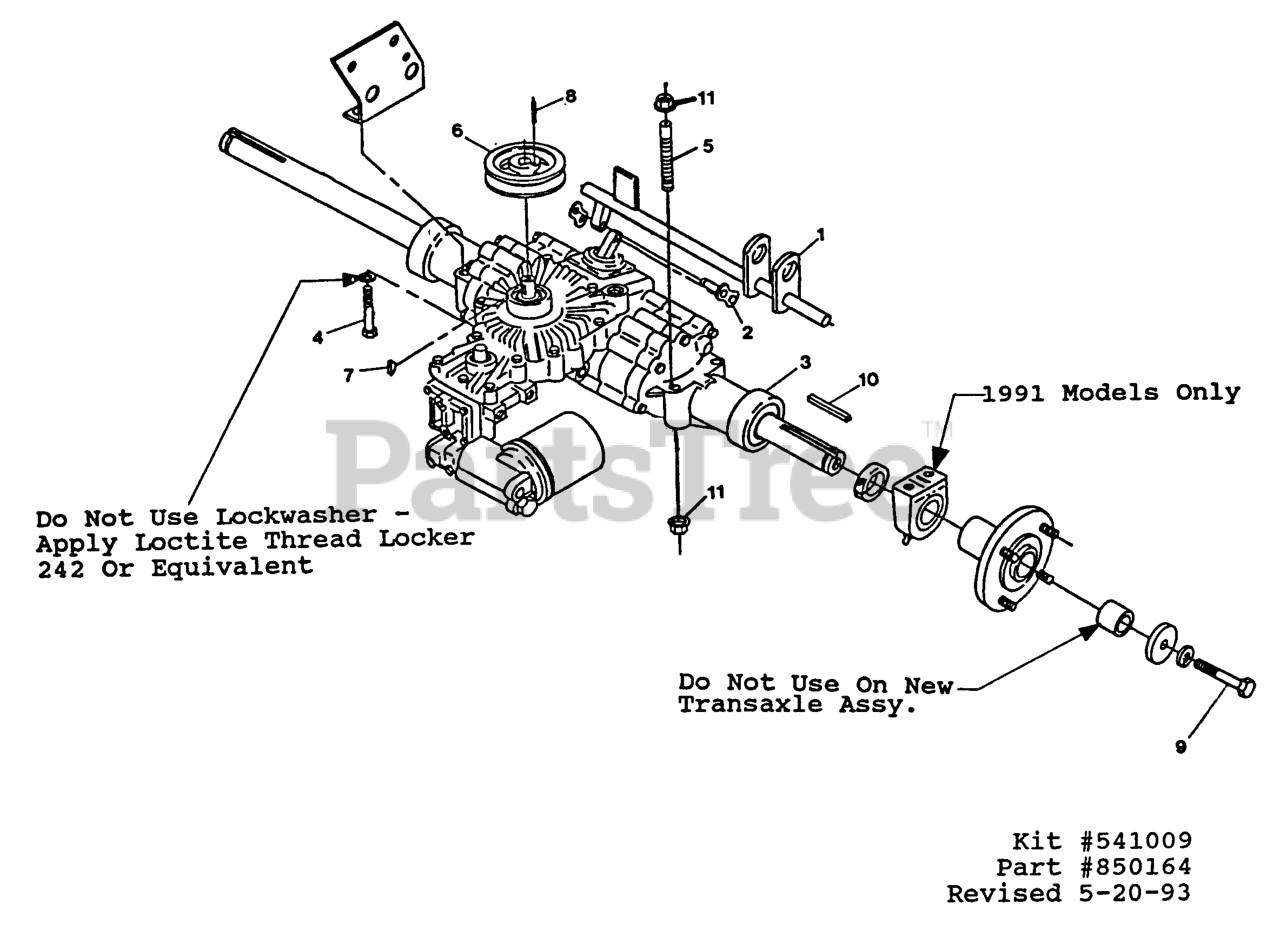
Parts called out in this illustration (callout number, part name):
1	Jackshaft Wldmt - Brk
2	LINK,CONNECTING
5	PIN,GUIDE
10	KEY,MACH HRD
